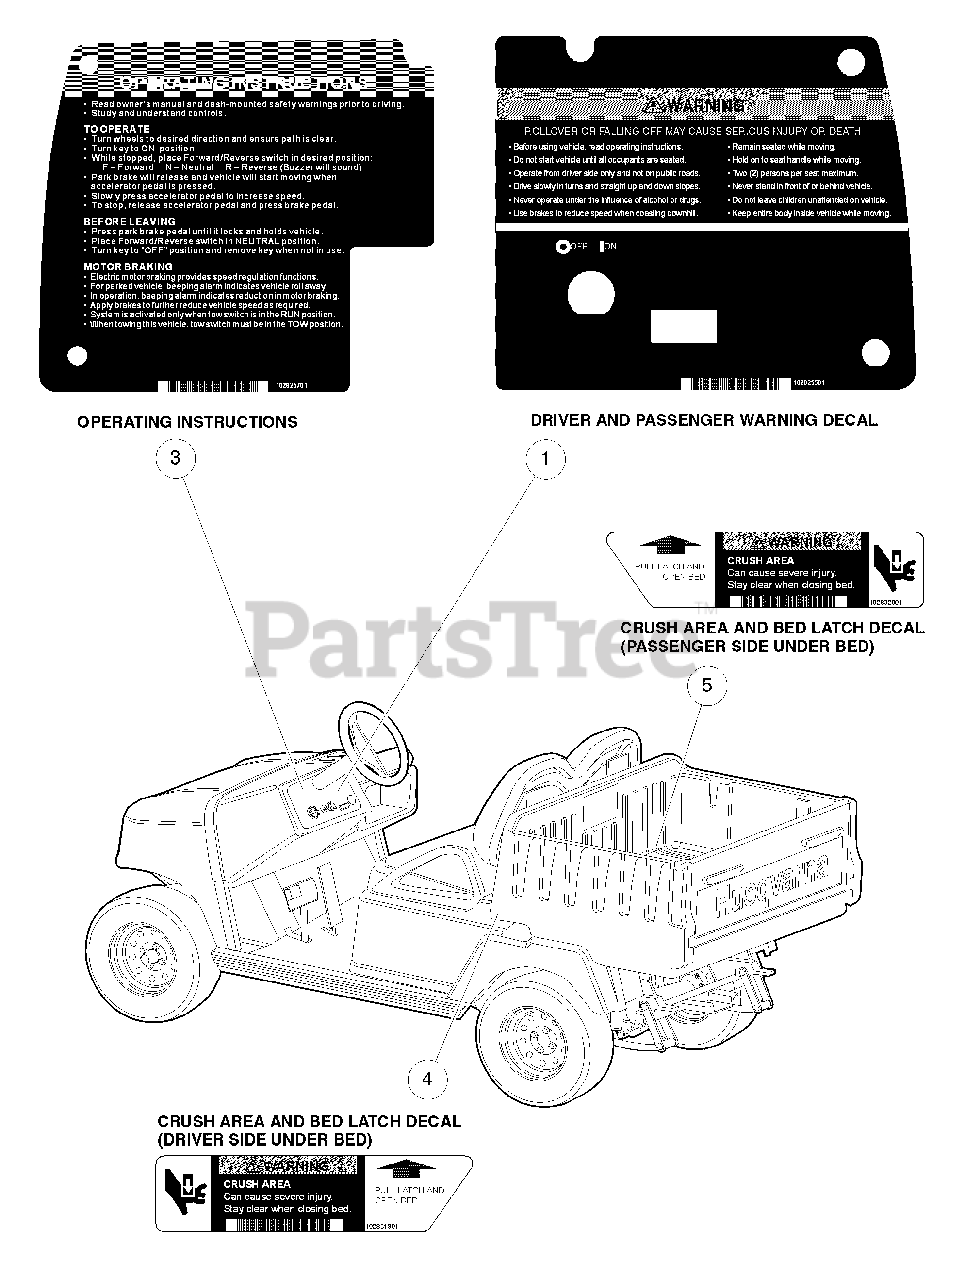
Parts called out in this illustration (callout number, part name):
1	Decal, Warning, Instrument Panel
3	Decal, Operating Instructions, Instrument Panel
4	Decal, Crush Warning, Driver-Side
5	Decal, Crush Warning, Passenger-Side
